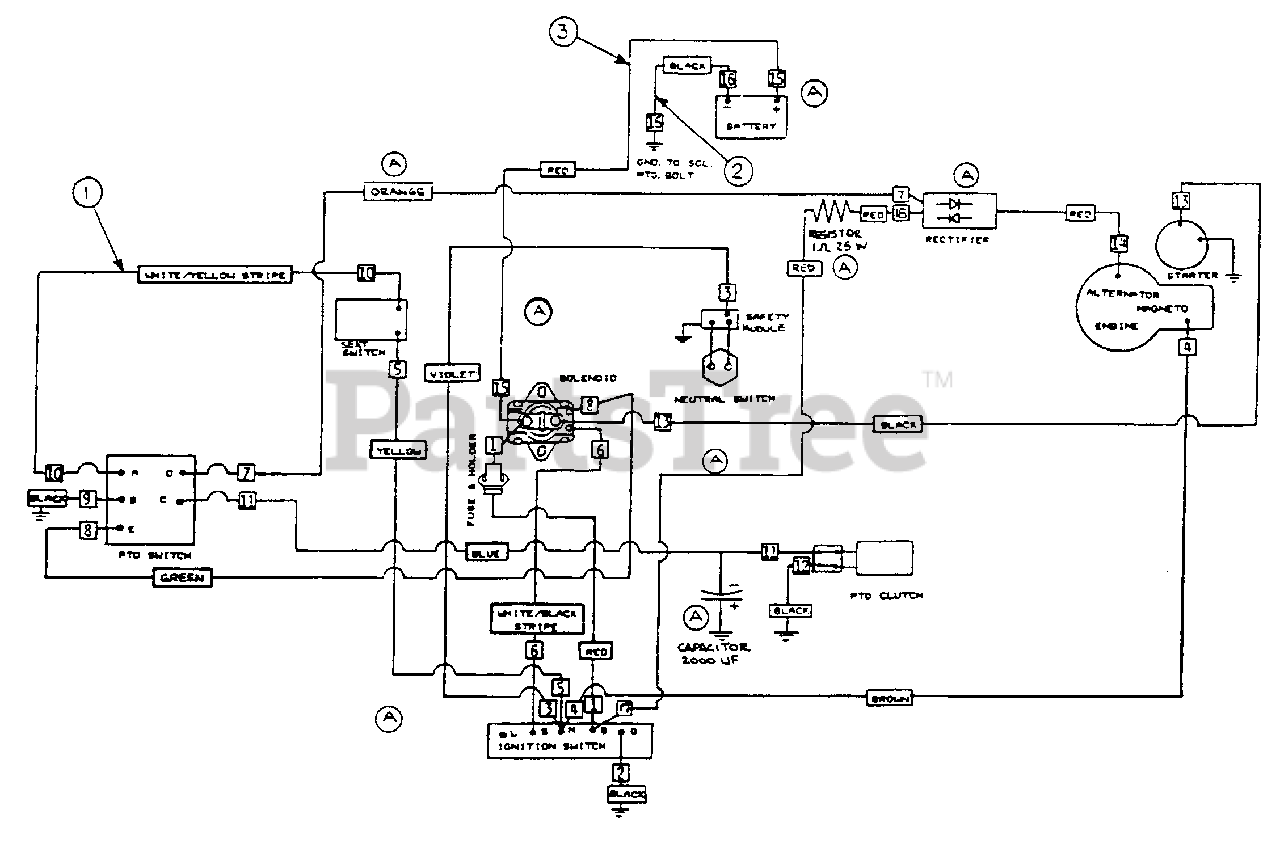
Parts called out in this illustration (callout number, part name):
1	WIRE HARNESS
2	BATTERY CABLE- Ground
3	BATTERY CABLE
